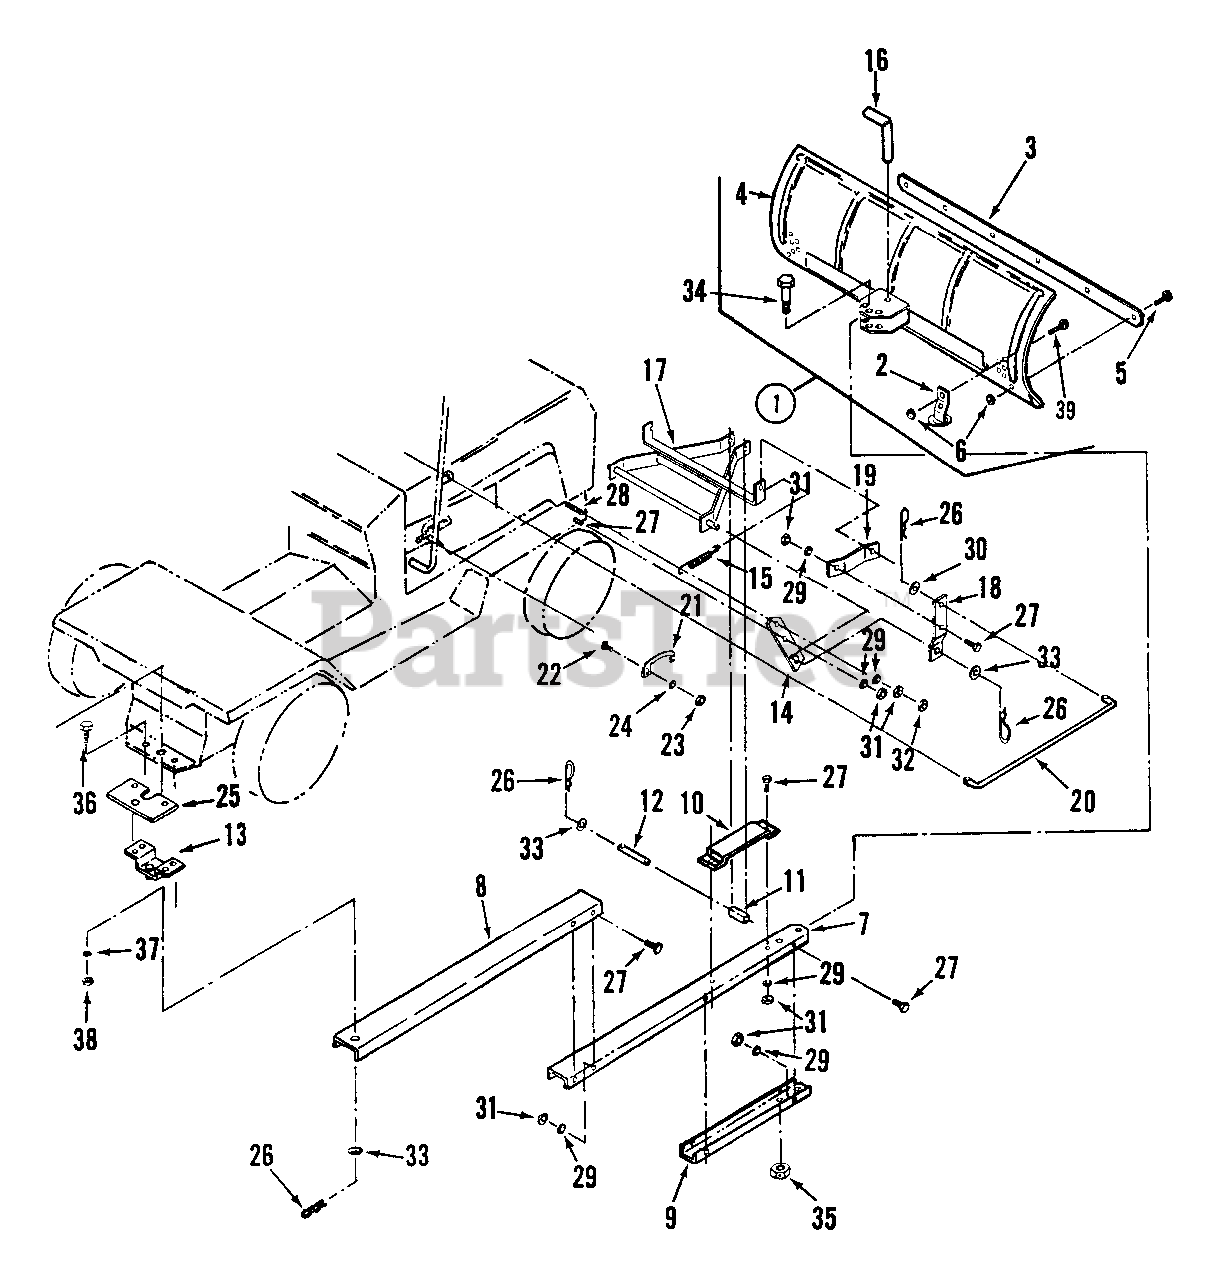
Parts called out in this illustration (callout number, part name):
1	ASSEMBLY, 42" Blade
2	STRUCTURE, Slide
3	SCRAPER
5	BOLT, 3/8-16 x 3/4" Square Neck Carriage, Gr. 2
6	NUT, 3/8-16 Hex Center Lock, Grade B or 5
7	BEAM, Front
8	BEAM, Rear
9	PLATE, Front Hitch
10	BRACKET, Lift
11	ROLLER, Lift
12	PIN, Lift Roller
13	HITCH WELDMENT, Rear Yoke
14	PLATE, Side Support
15	SPRING, Lift Assist
16	PIN, Latch
17	STRUCTURE, Lift Yoke
18	ARM, Lift
20	ROD, Operating
21	PLATE, Quadrant Lockout
22	BOLT, 1/4-20 x 5/8" Flat Head Carriage
23	NUT, 1/4-20 Hex
24	WASHER, 1/4 Internal Tooth Lock
25	DRAWBAR, Short Auxilliary
26	PIN, Hair Cotter
27	SCREW, 3/8-3/8-16 x 1" Hex Head Cap, Grade 5
28	SCREW, 3/8-16 x 1-1/2" Hex head Cap, Grade 5
29	WASHER, 3/8 Split Lock
30	WASHER, 3/8" Flat
31	NUT, 3/8-16 Hex, Grade 5
32	NUT, 3/8-16 Hex Center Lock, Grade B or 5
33	WASHER, 1/2 Flat
34	SCREW, 1/2-20 x 2-3/4" Hex Head Cap
35	NUT, 1/2-20 Nyloc
36	SCREW, 5/16-18 x 3/4" Hex Head Cap, Grade 2
37	WASHER, 5/16 Split Lock
38	NUT, 5/16-18 Hex
39	BOLT, 3/8-16 x 1" Square Neck Carriage, Grade 2
